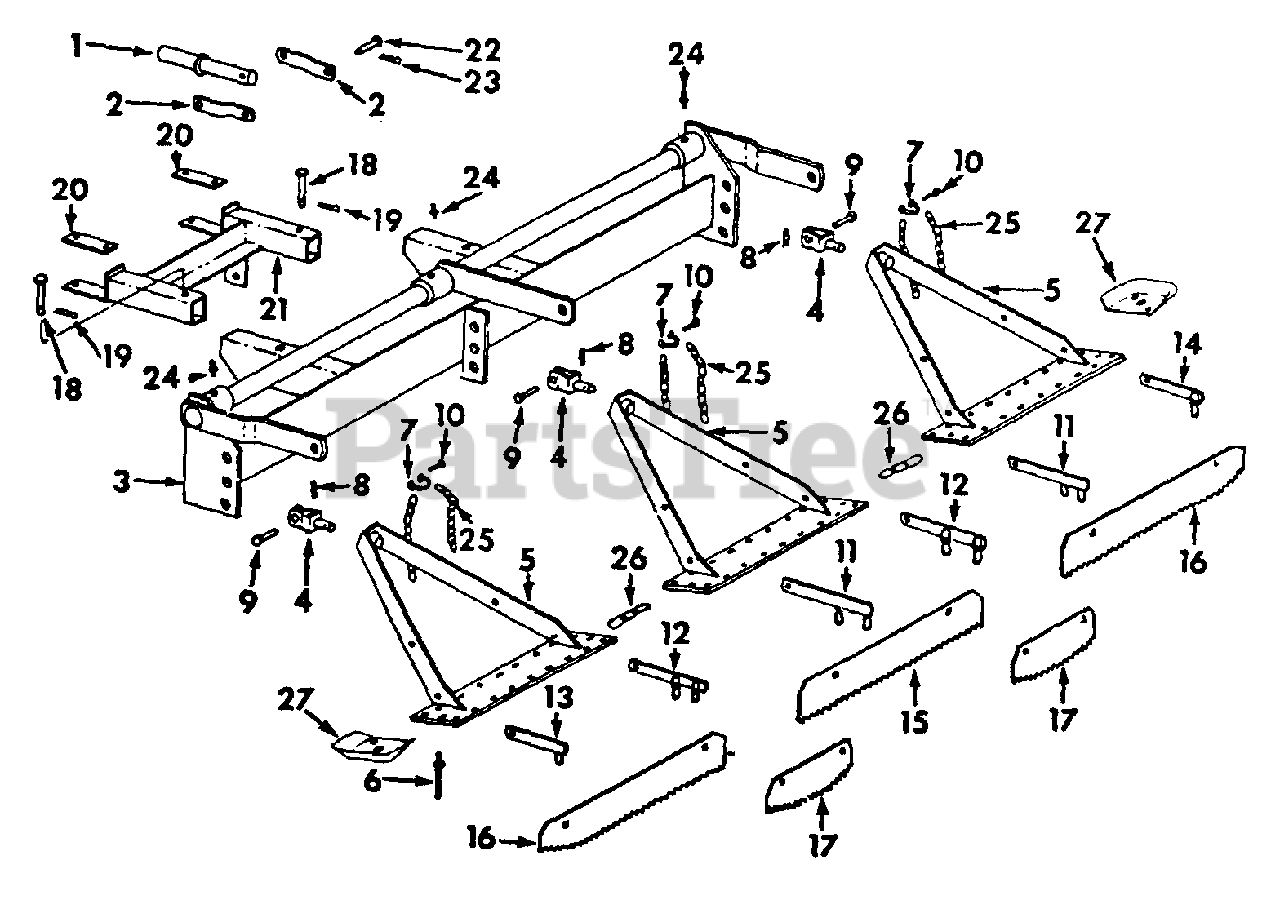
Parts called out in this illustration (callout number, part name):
1	BAR, LIFT
2	LINK, LIFT
3	LIFT, RAKE
4	CLEVIS, SWIVEL
5	SUPPORT, FRONT RAKE PIVOT
7	CLEVIS
8	PIN, QUICK ATTACHABLE COTTER
9	PIN, 1/2 x 1-7/16 C-Z STD-HD
10	PIN, 1/4 x 1-1/8 C-Z STD-HD
11	BAR W/CHAIN, RH
12	BAR W/CHAIN, LH
13	SUPPORT W/CHAIN, RH
14	SUPPORT W/CHAIN, LH
15	BLADE, REAR CENTER RAKE
16	BLADE, REAR CENTER RAKE
17	BLADE, REAR CENTER RAKE
19	PIN, QUICK ATTACHABLE COTTER
20	PLATE, AXLE TIE
21	BRACKET, TRACTOR MOUNTING
22	PIN, 3/8 x 2-1/8 C-Z STD-HD
23	PIN, HAIR
24	FITTING, 1/4 UNF STR LUB
25	CHAIN, 9 LINKS 3/16 GALV
26	CHAIN, 1/4 PROOF LINK
27	SKID
137273	PIN, 3/16 x 2-1/2 C-Z COTTER
